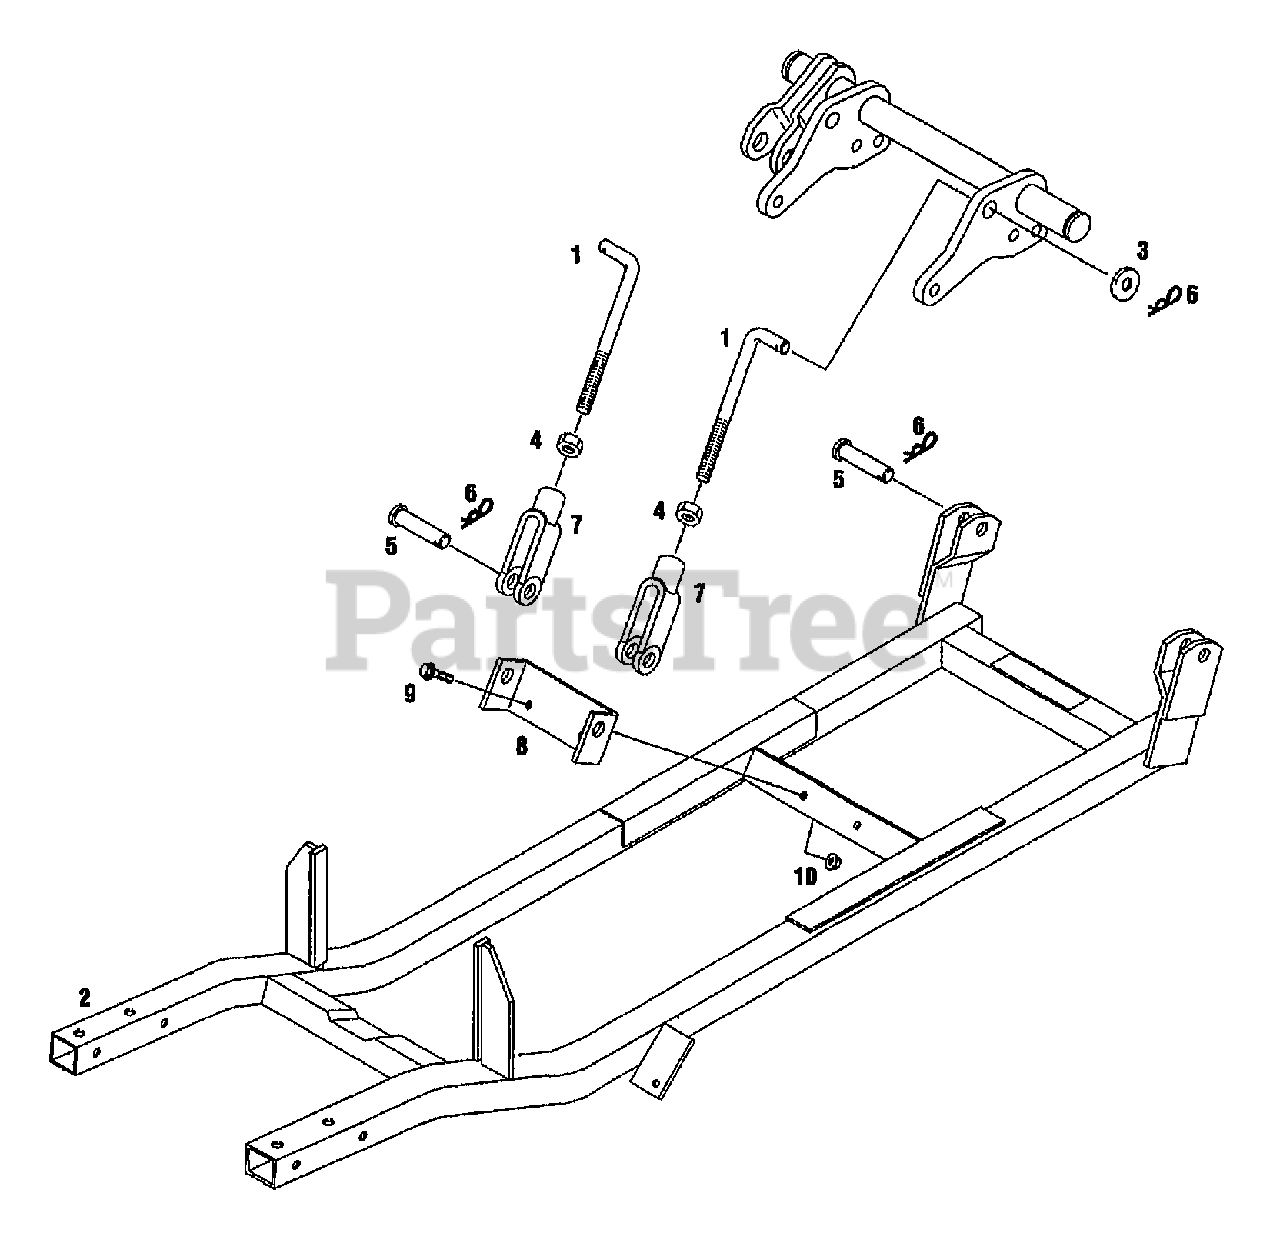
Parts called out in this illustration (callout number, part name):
1	ROD-LIFT
2	ARM-PUSH
3	WASHER-1.305X.649X.098 ZP
4	NUT-HEX
5	PIN-CLEVIS
6	PIN-HITCH .125X2.56 ZP
7	ROD-END
8	BRKT-LIFT
9	SCR-HFLK 3/8-16X1.25 ZP
10	NUT-HFLK 3/8-16 ZP
